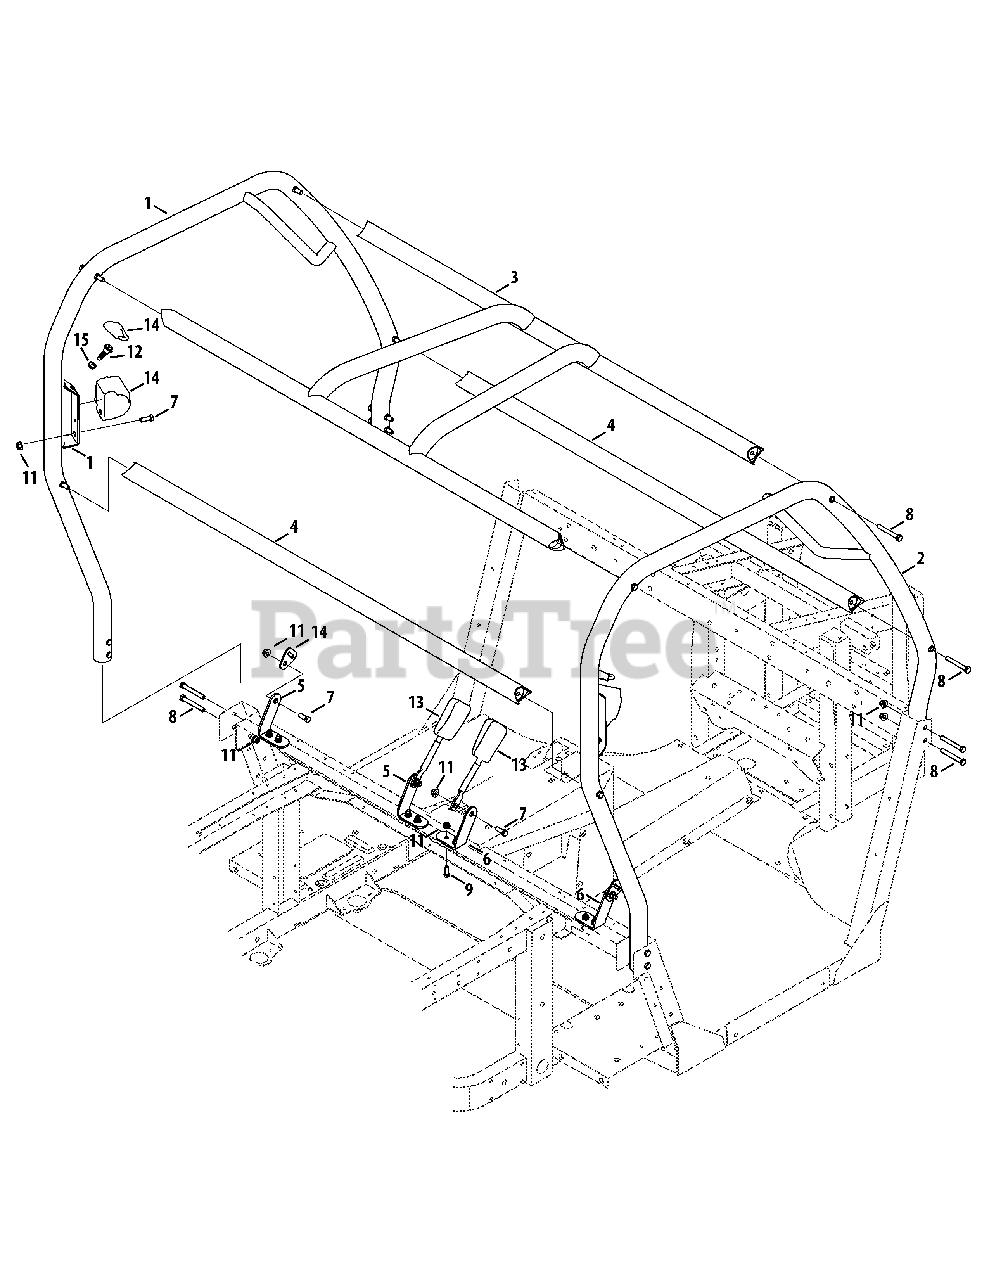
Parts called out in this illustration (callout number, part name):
1	Frame Assembly, OPS, LH
2	Frame Assembly, OPS, RH
3	Frame Assembly, OPS, Roof
4	Frame Assembly, OPS, Frt
6	Bracket, Seat Belt, RH
7	Screw, 3/8-16 x 1.00
8	Screw, 3/8-16 x 2.75
9	Screw, 5/16-18 x .875
10	Nut, Flange Lock, 5/16-18
11	Nut, Flange Lock, 3/8-16
12	Shoulder Bolt, 7/16-20
14	Belt, Seat
15	Nut, Hex Lock, 7/16-20
